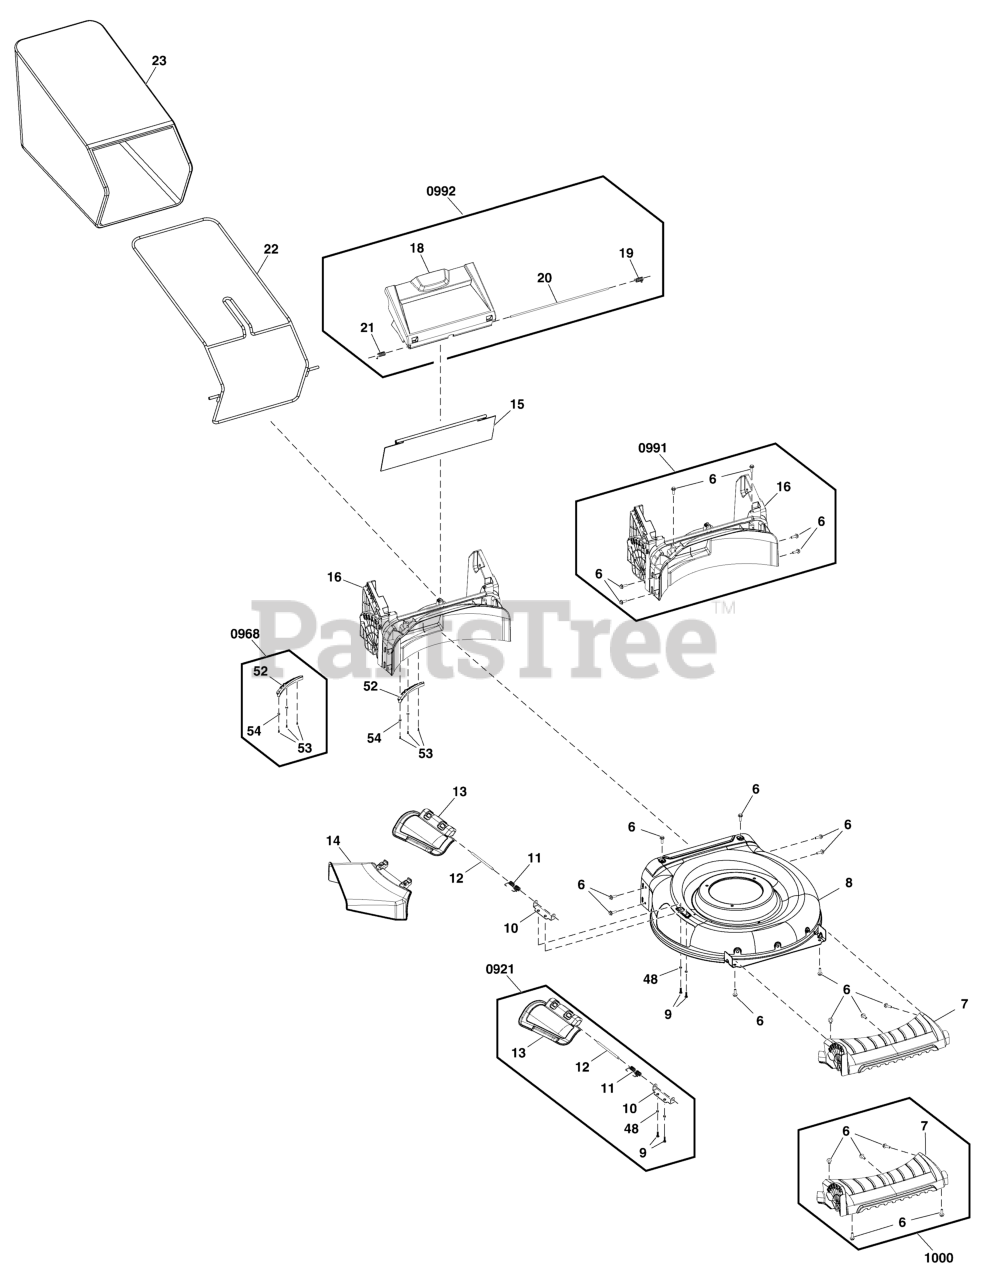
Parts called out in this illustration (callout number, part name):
6	SCREW, Hex Head
7	HOUSING, Front
8	DECK
9	SCREW
10	BRACKET, Deflector
11	SPRING, Deflector
12	SHAFT, Deflector
13	COVER, Mulch
14	DEFLECTOR
15	COVER, Dust
16	HOUSING, Rear
18	COVER, Rear
19	SPRING, Left
20	SHAFT, Rear Cover
21	SPRING, Right
22	FRAME, Catcher, Grass
23	CATCHER, Grass
48	WASHER
52	PLUG, Rear
53	SCREW
54	WASHER, Flat
0921	KIT, Mulching
0968	KIT, Plug
0991	KIT, Housing, Rear
0992	KIT, Deflector, Rear
1000	KIT, Housing, Front
